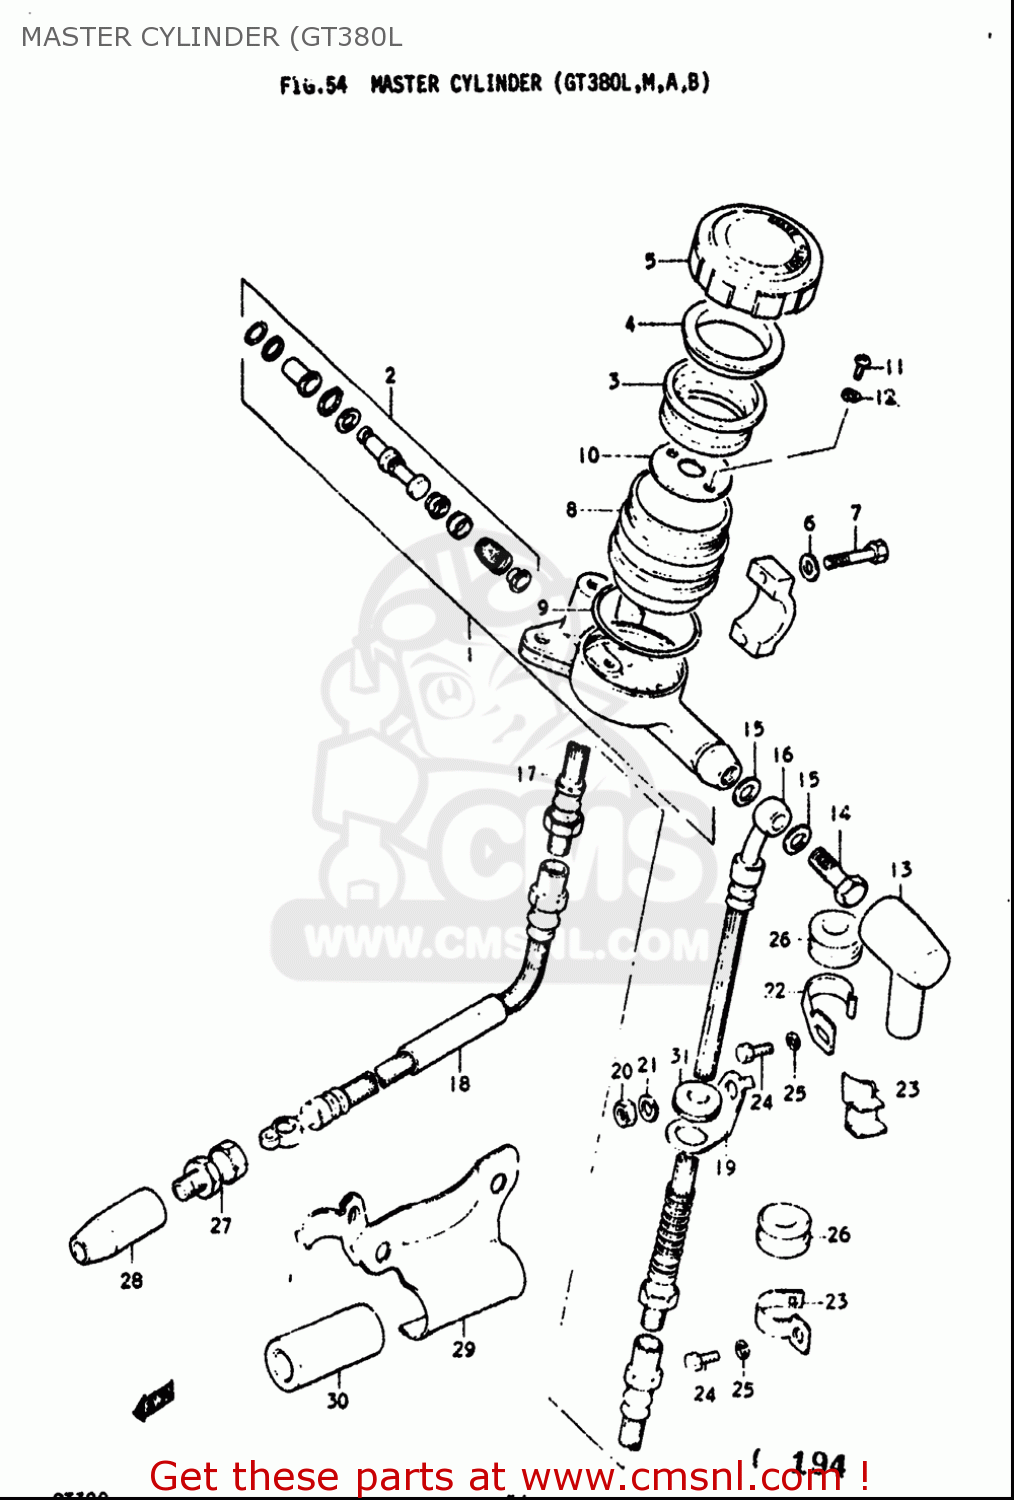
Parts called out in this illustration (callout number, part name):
2	PISTON & CUP SET
3	DIAPHRAGM
4	PLATE
5	CAP
6	WASHER
7	BOLT
8	RESERVOIR
9	O RING
11	SCREW
12	WASHER,LOCK
13	BOOT,MASTER CYLINDER
14	BOLT UNION
15	WASHER(10X15X1.5)
18	HOSE,BRAKE NO.3
20	NUT
21	WASHER,LOCK
24	SCREW(6X12)
25	WASHER,LOCK
26	BUSH
30	CUSHION
31	GROMMET
